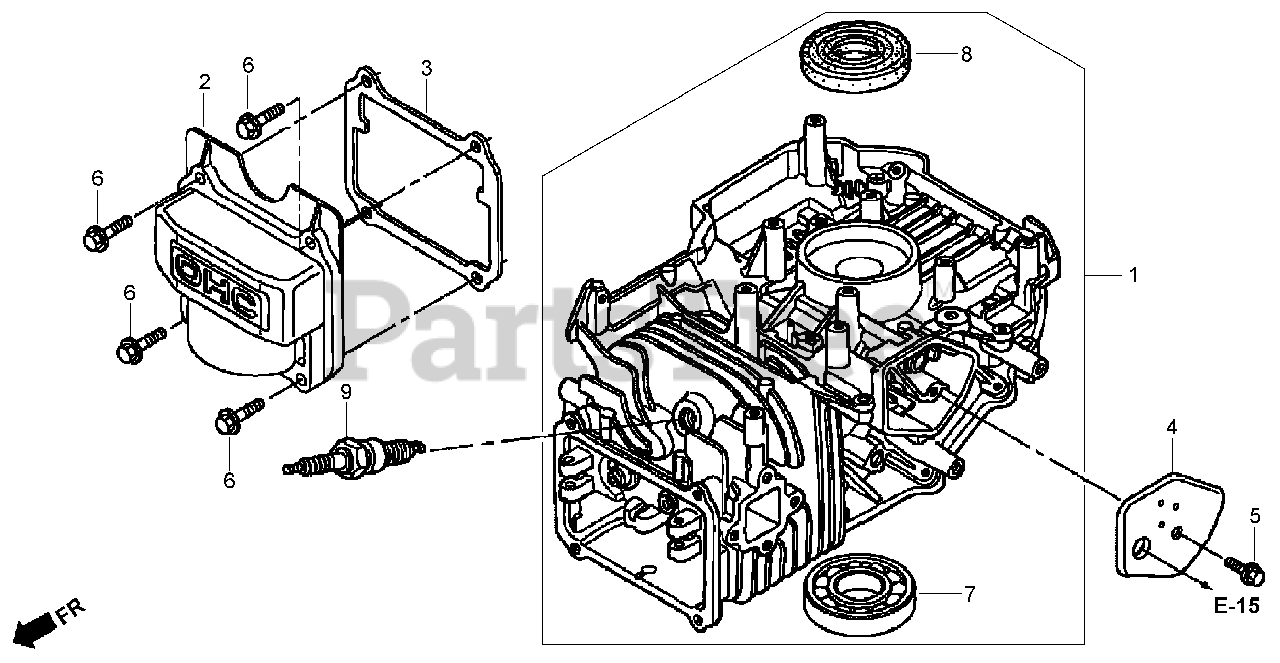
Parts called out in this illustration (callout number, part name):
1	CYLINDER ASM
2	COVER-HEAD, CYLINDER
3	GASKET-COVER, HEAD
4	COVER-BREATHER (BREATHER VALVE ASM)
5	BOLT-FLANGE (6X14) (C T200)
6	BOLT-FLANGE (6X25) (C T 200)
7	BEARING-BALL, RADIAL
8	SEAL-OIL (25.4X74X6)
9	SPARK PLUG (B P R 6E S) (N G K)
